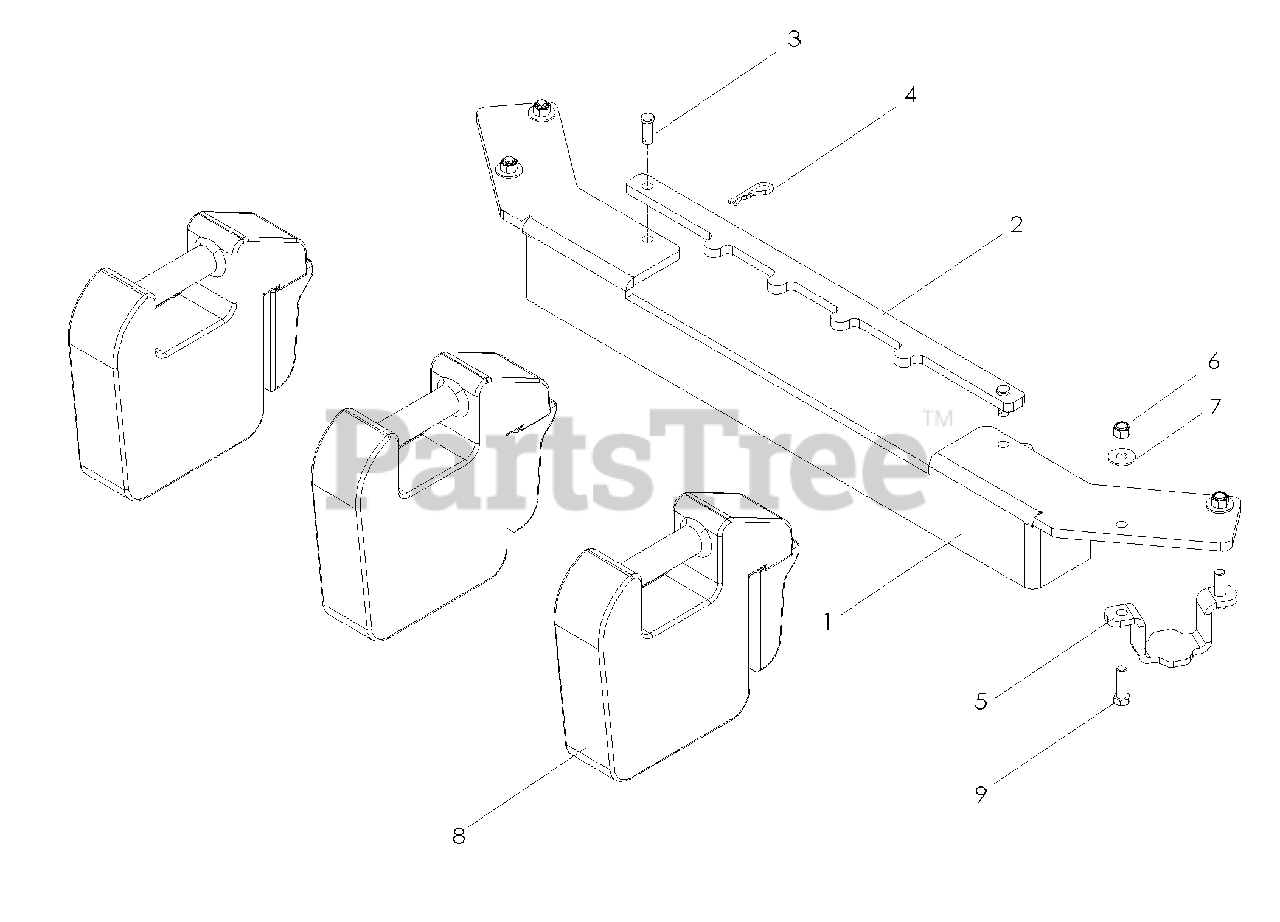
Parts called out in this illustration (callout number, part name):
1	WEIGHT BAR, FRONT
2	HOLD DOWN, WEIGHT BAR
3	CLEVIS PIN
4	SPRING RETAINER
5	WEIGHT KEEPER
6	NUT 3/8-16 HEX NYLOC
7	WASHER 3/8 STD FLT
8	CAST COUNTERWEIGHT
9	HCS 3/8-16 x 1 1/4
